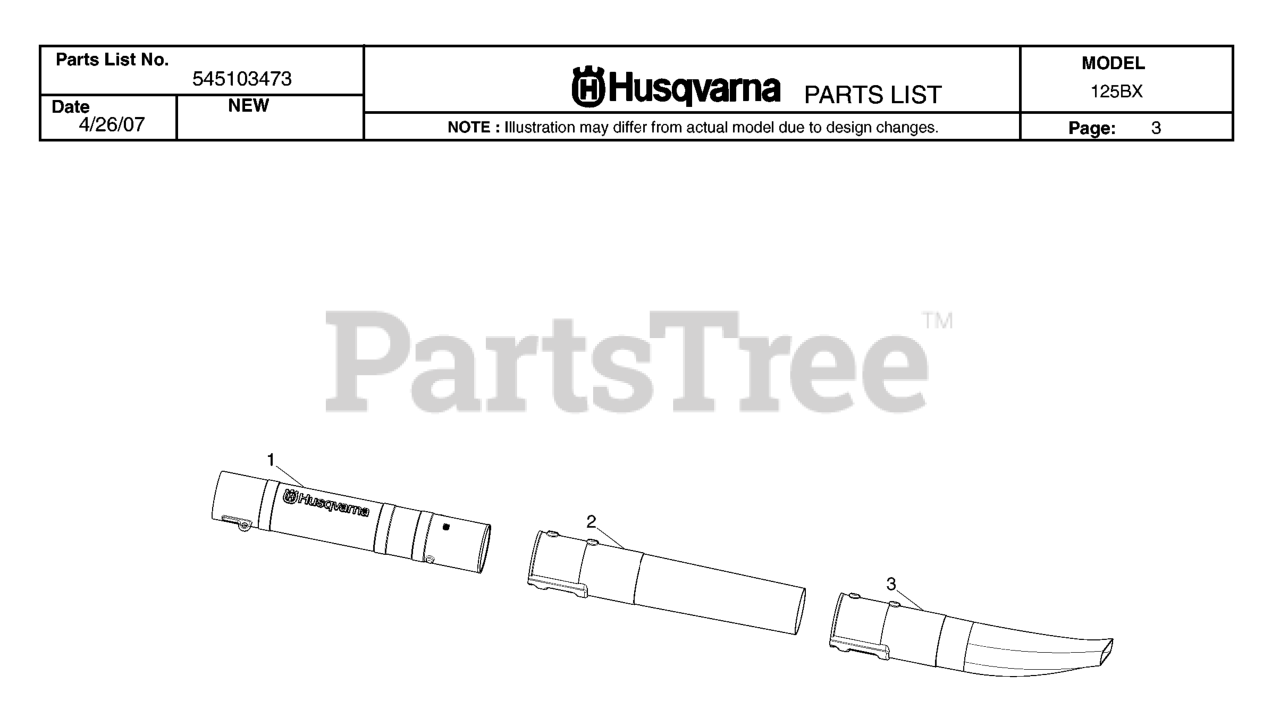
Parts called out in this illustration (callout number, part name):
1	ASSY TUBE BLOWER W/BARR
2	TUBE, LOWER
3	FLARE, LOWER TUBE
